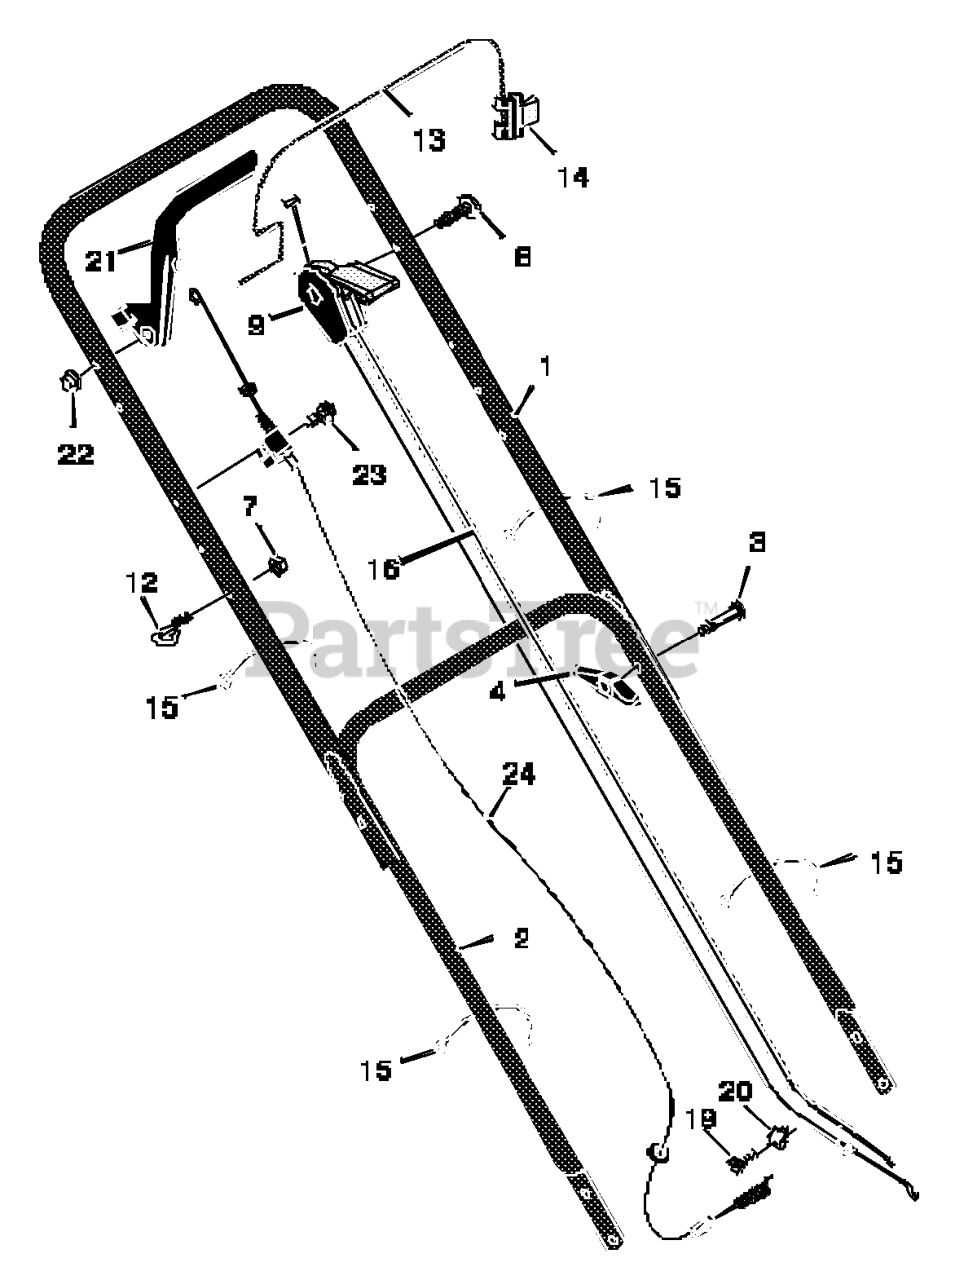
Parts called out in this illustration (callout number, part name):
1	Handle, Upper (Black)
2	Handle, Lower (Black)
4	Knob, Plastic
7	Locknut
9	Throttle Control
12	GUIDE, ROPE
13	Stop Lever - Straight
14	Bracket, Stop Lever
15	Fastener, Cable
16	Engine Stop Cable
19	Screw *
20	Clamp
21	Lever, Drive
22	Push On Cap
24	Cable, Drive
